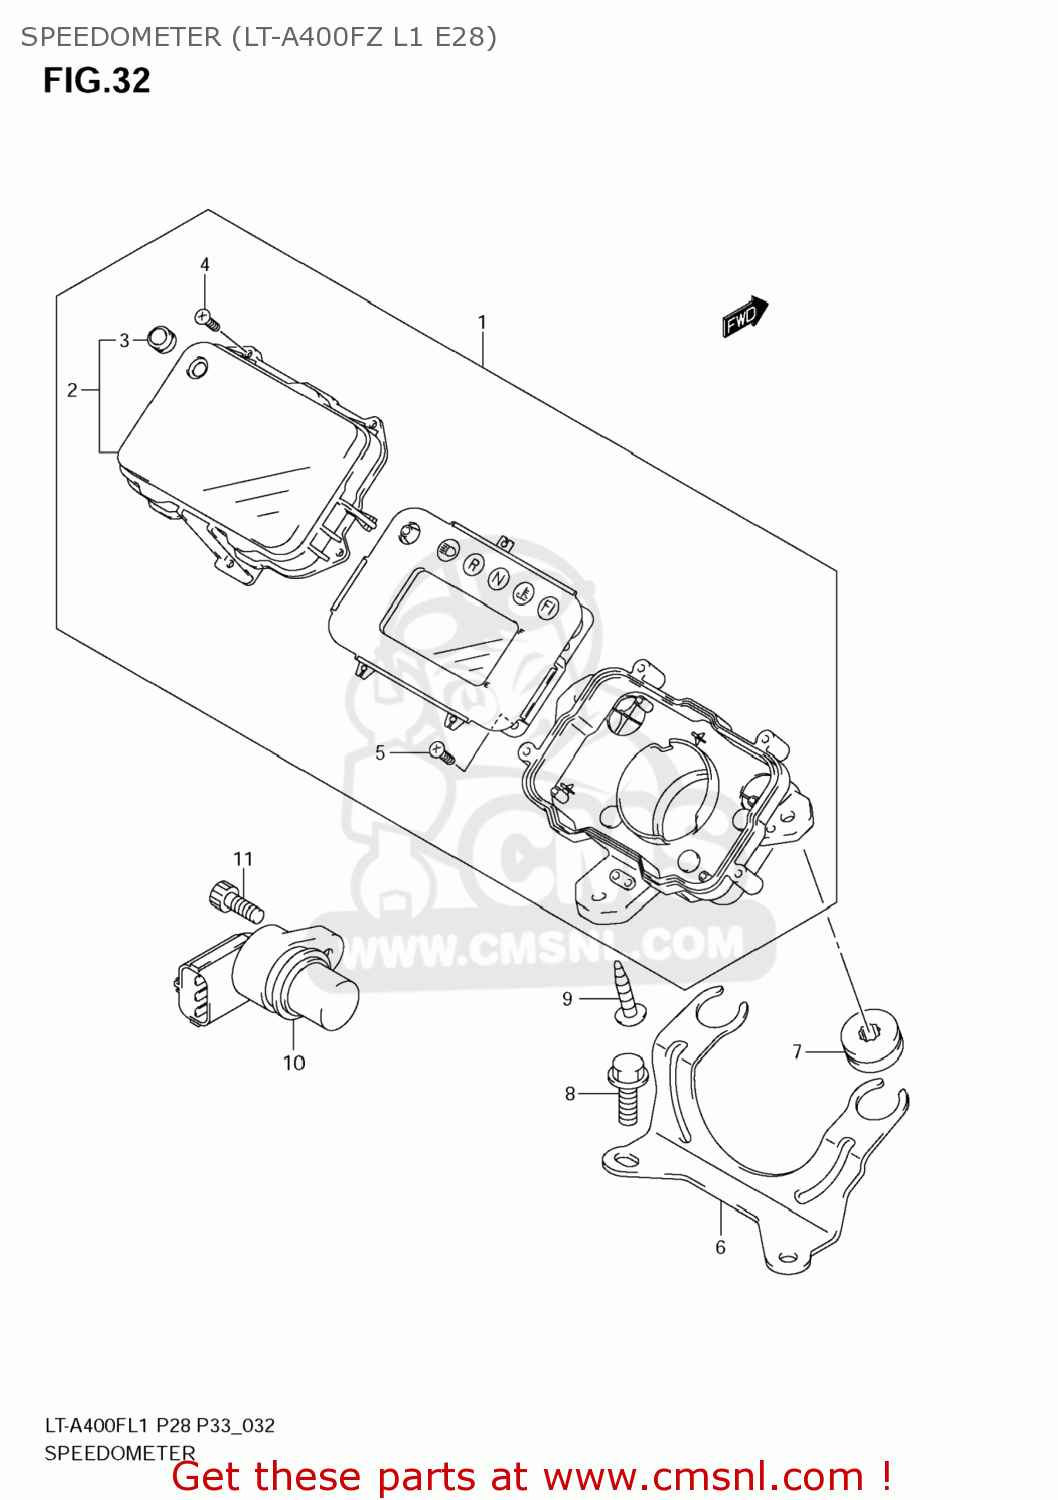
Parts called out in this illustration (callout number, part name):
1	SPEEDOMETER ASSY
2	CASE,UPR
3	SWITCH,RUBBER
4	SCREW(3X12)
5	SCREW(3X12)
6	BRACKET,SPEEDOMETER
7	CUSHION
8	BOLT
9	SCREW
10	SENSOR,SPEED
11	BOLT
